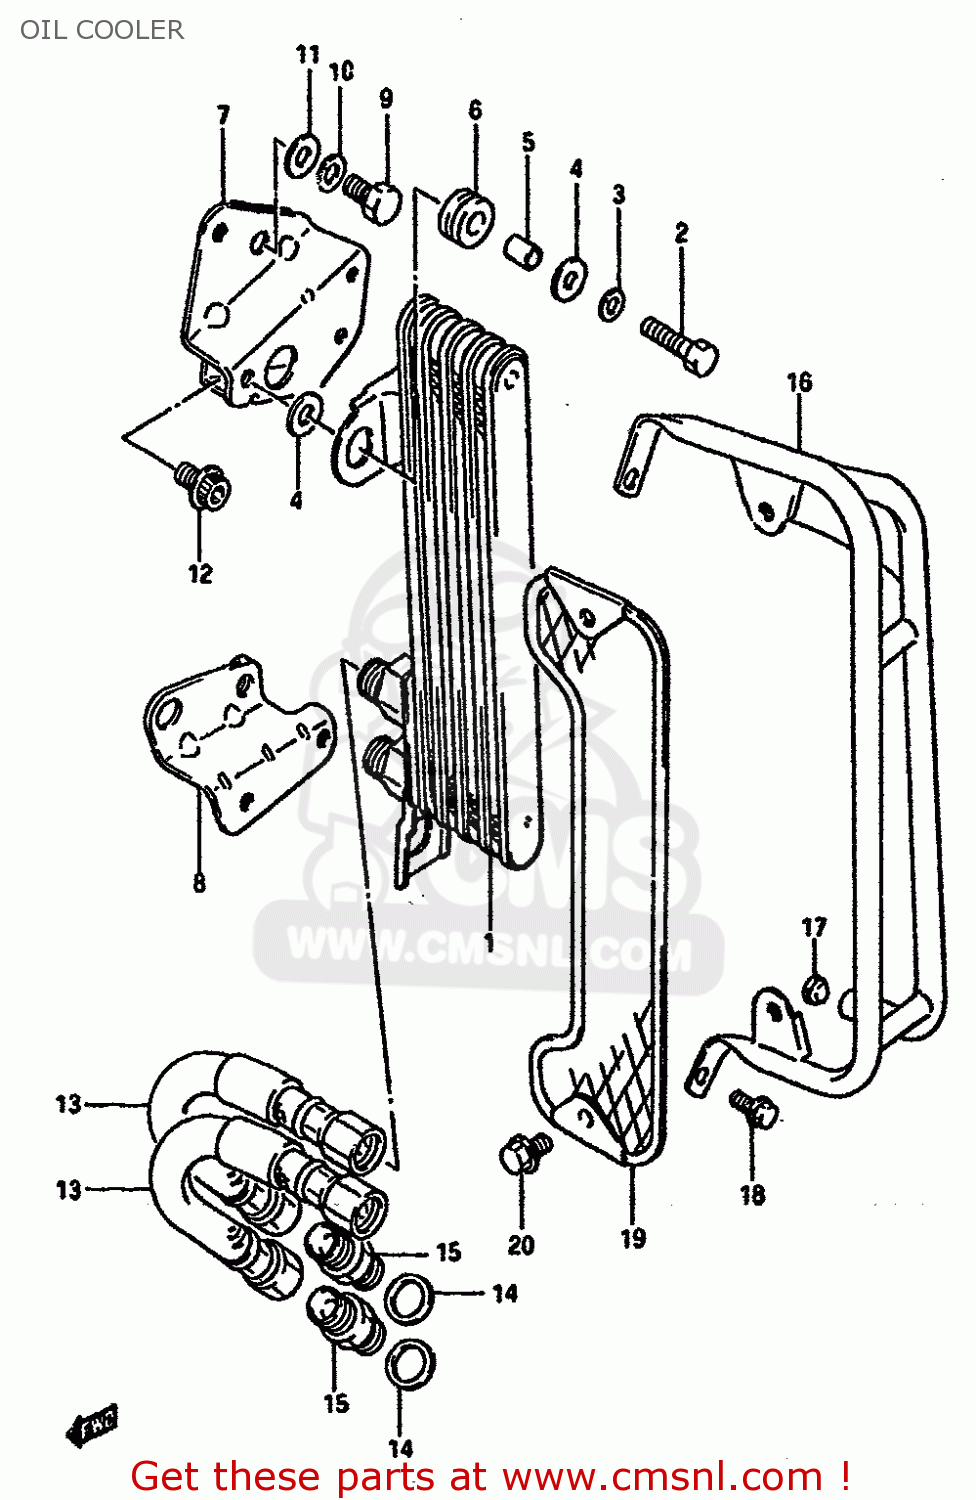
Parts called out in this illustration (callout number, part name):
1	COOLER ASSEMBLY,ENGINE OIL
2	BOLT
3	WASHER,LOCK
4	WASHER (6.5X18X1.6)
5	SPACER (6.8X10X10)
6	CUSHION
7	BRACKET,OIL COOLER NO.1
8	BRACKET,OIL COOLER NO.2
9	BOLT
10	WASHER,LOCK,8.
11	WASHER
12	BOLT
13	HOSE,OIL COOLER
14	GASKET(14X20X1.5) (NAS)
15	BOLT UNION
16	GUARD,OIL COOLER
17	CAP(OD:10)
18	BOLT
19	BUMPER,OIL COOLER
20	BOLT 6X12
